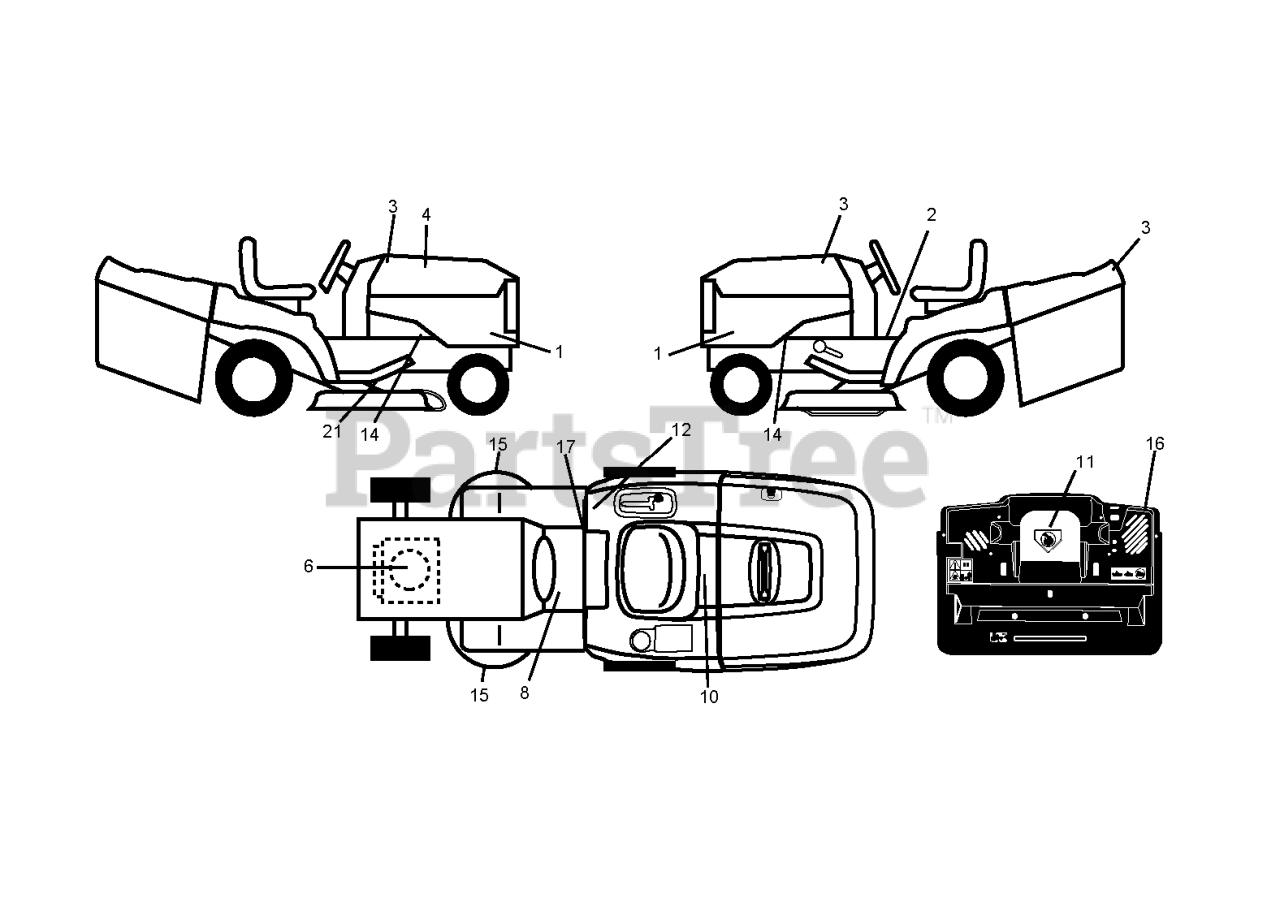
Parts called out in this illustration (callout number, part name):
2	LABEL
3	DECAL.HOOD.NAMELOGO.HUSQ
6	DECAL
8	DECAL
10	DECAL BTRY SYMBOLS
11	DECAL.INTERNATIONL.CUTFINGER
12	Decal, Fender 100 DB/CE
16	DECAL
17	DECAL PARK BRAKE
